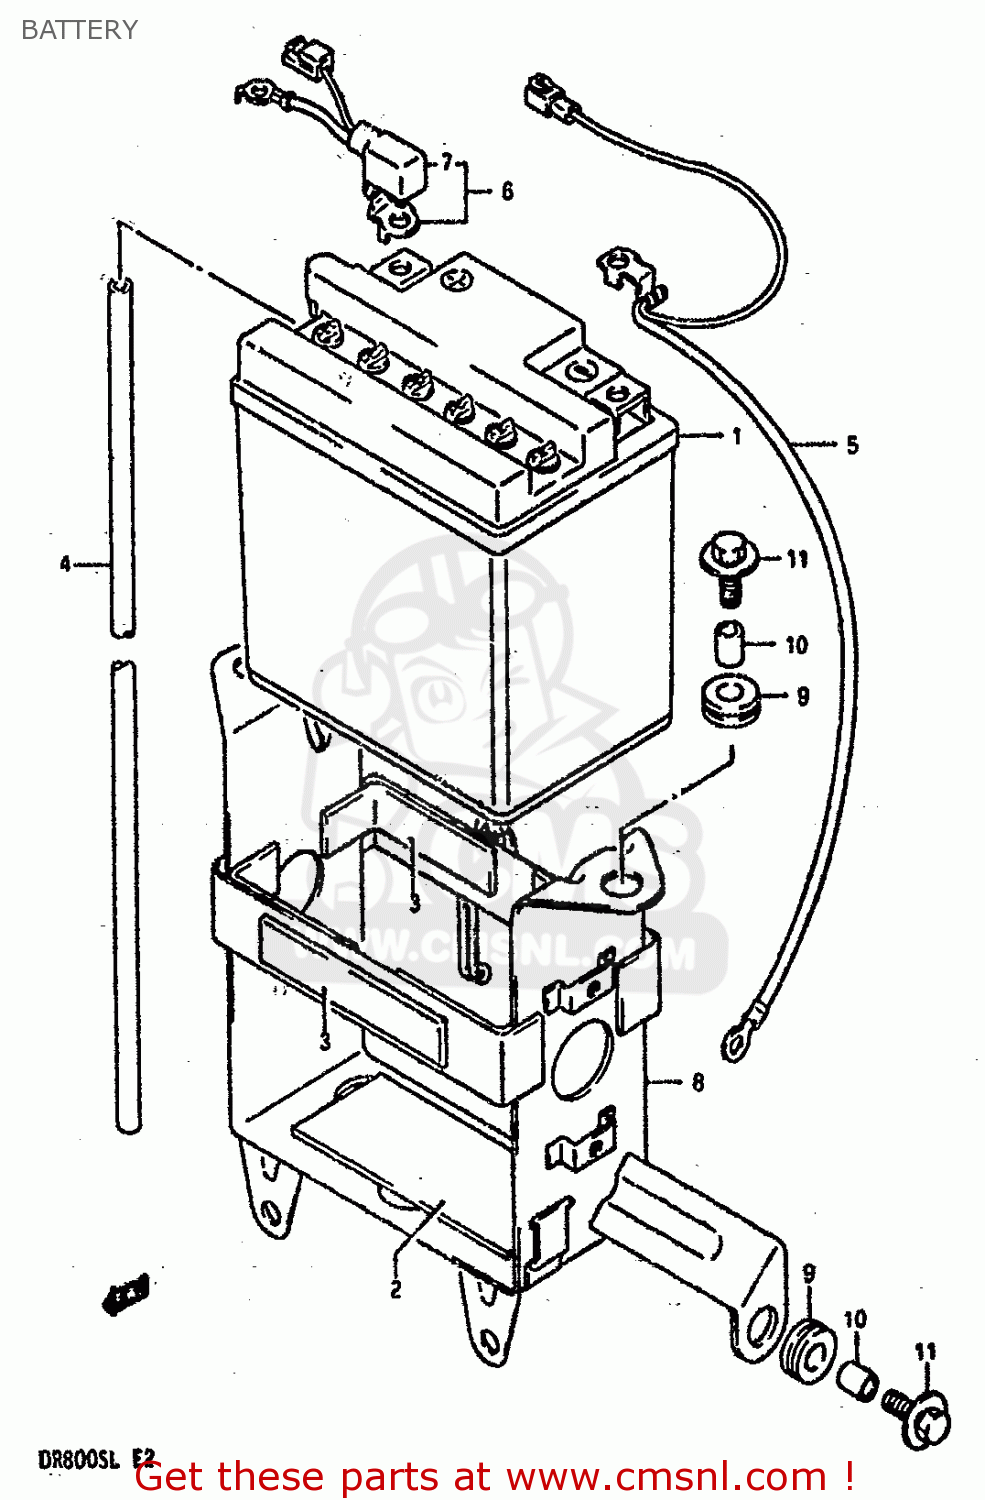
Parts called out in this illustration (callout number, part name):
1	BATTERY(YB14L-B2,12V14.7AH)
2	PROTECTOR(170X95X3.0)
3	PROTECTOR,20X9
4	HOSE,BATTERY EXHAUST
5	LEAD WIRE,BATTERY (-)
6	LEAD WIRE,BATTERY (+)
7	CAP,BATTERY PLUS
8	HOLDER,BATTERY
9	CUSHION
10	SPACER(6.1X9X7.5)
11	BOLT 6X20
